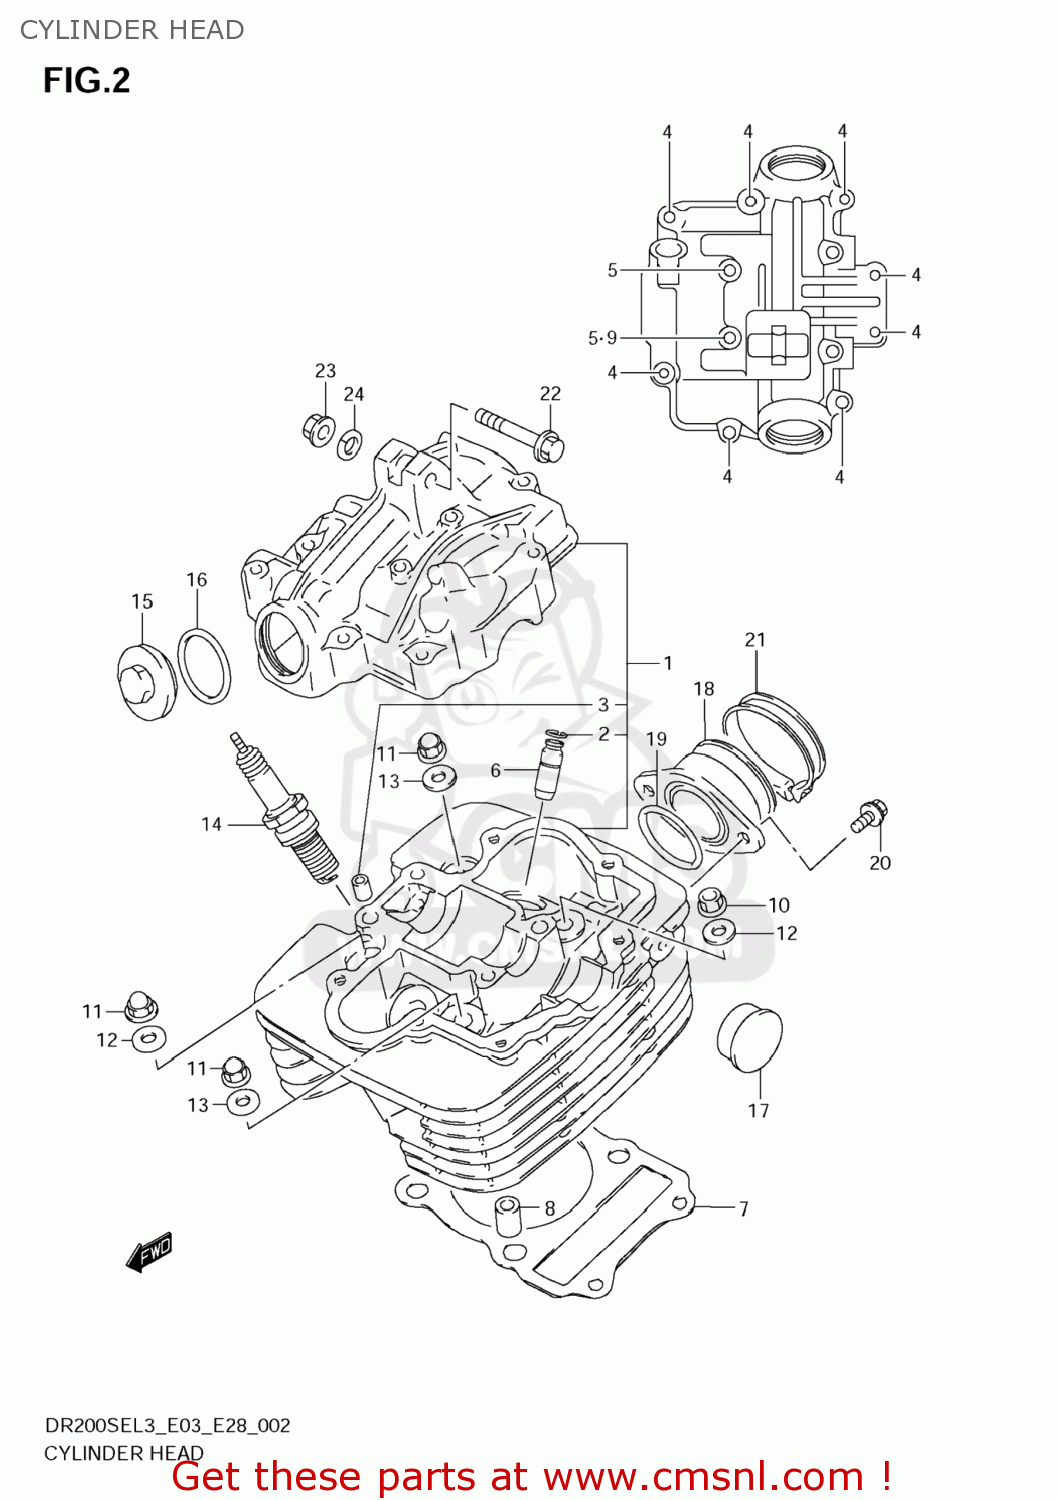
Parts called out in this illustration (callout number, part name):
1	HEAD ASSY,CYLINDER
2	RING,SNAP
3	PIN(6.2X8X11)
4	BOLT
5	BOLT
6	GUIDE,VALVE
7	GASKET,CYLINDER HEAD (NAS)
8	PIN
9	GASKET(5.8X13X1.2) (NAS)
10	NUT
11	NUT
12	WASHER(8.5X19X2.3)
13	GASKET(8.5X17X2.3) (NAS)
14	PLUG,SPARK(DR8EA)
15	CAP,INSPECTION
16	O RING(D:3,ID:29.5)
17	PLUG(OD:22.5)
18	PIPE,INTAKE
19	O RING(D:1.9,ID:34.6)
20	SCREW
21	CLAMP
22	BOLT(8X55)
23	NUT
24	WASHER,LOCK
